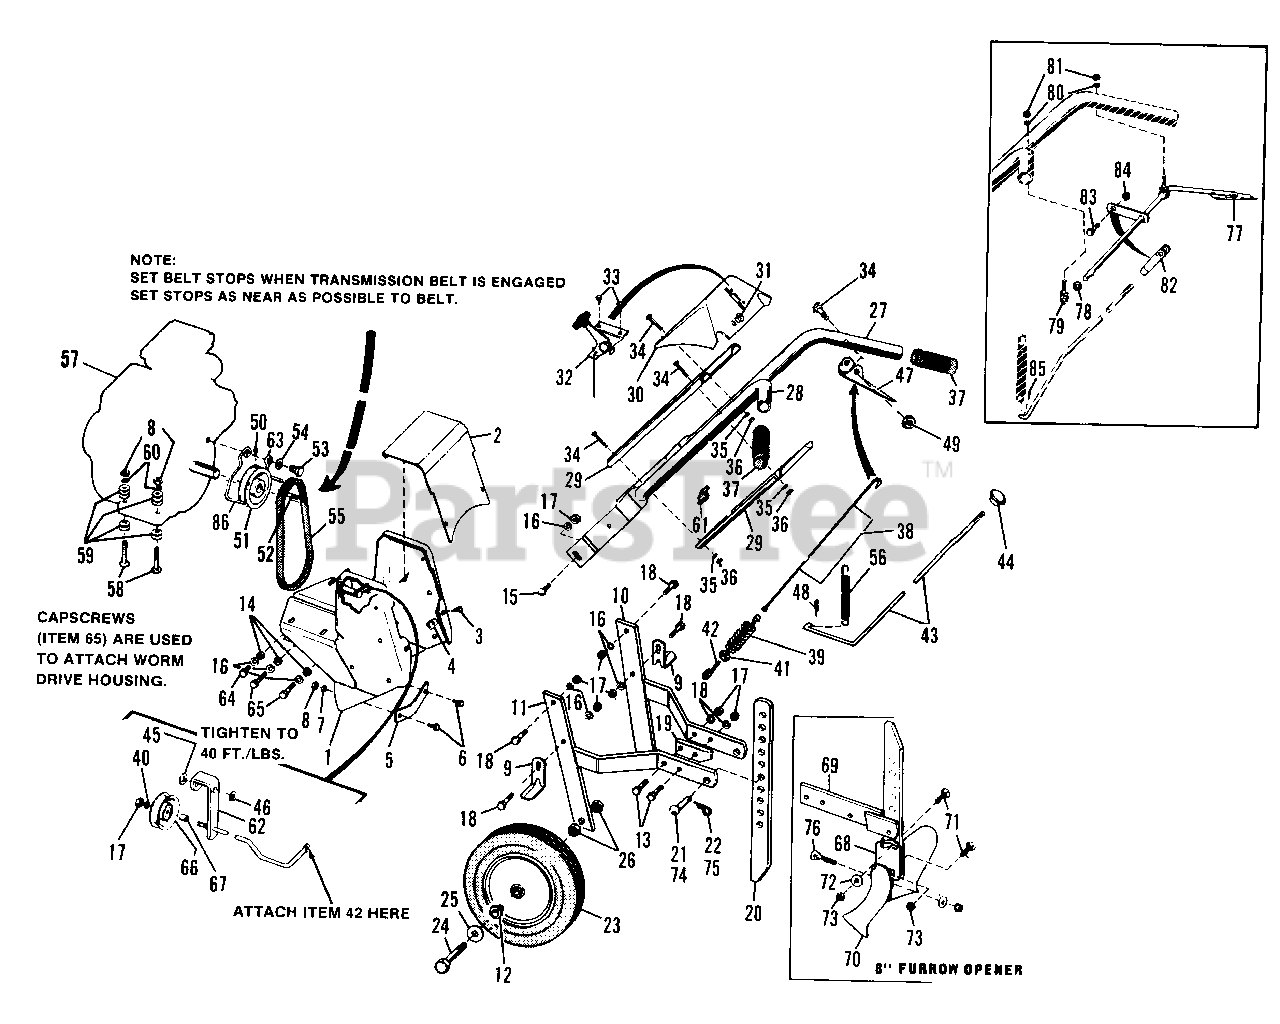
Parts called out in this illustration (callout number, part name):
1	BODY ASSY
2	BODY COVER
3	SCREW, Thumb
4	NUT, Speed
5	SUPPORT, Shaft
6	CAPSCREW, Hex, 5/16-18 x 5/8
7	LOCKWASHER, 5/16
8	NUT, Hex, Full, 5/16-18
10	SUPPORT ASSY, R.H.
11	SUPPORT ASSY, L.H.
12	BUSHING, Wheel
13	CAPSCREW, Hex, 3/8-16 x 1-1/2
14	NUT, Hex, Full, 3/8-16
15	BOLT, Carriage, 3/8-16 x 3/4
16	LOCKWASHER, 3/8
17	NUT, Hex, Full, 3/8-16
18	CAPSCREW, Hex, 3/8-16 x 1-1/4
19	PLATE, Stop
20	BAR, Depth
21	PIN
22	CLIP, Spring
23	WHEEL & TIRE ASSY
24	CAPSCREW, Hex, 1/2-13 x 3-1/4
25	WASHER, Plain, 1/2
26	NUT, Hex, Jam, 1/2-13
27	HANDLE, L.H.
27	HANDLE, R.H.
28	HANDLE, L.H.
29	COVER, Handle
30	HOUSING ASSY, Control
32	THROTTLE ASSY, control
33	SCREW, Self-Tapping, Hex, 1/4-20 x 1/2
34	CAPSCREW, Hex, 1/4-20 x 1-1/2
35	LOCKWASHER, 1/4
36	NUT, Hex, Full, 1/4-20
38	SPRING, Extension
38	ROD, Clutch
39	SPRING
40	LOCK WASHER, 3/8
41	NUT, Hex, Full, #10-24
42	EYEBOLT
43	ROD, Reverse
45	WASHER
46	RING, Retaining
47	GRIP, Clutch
48	PIN, Cotter
49	NUT, Hex, Full, 1/4-20
50	SETSCREW, 5/16-18 x 3/8
51	PULLEY
52	KEY
53	CAPSCREW, Hex, 1/2-20 x 3/4
53	CAP SCREW, Hex, 1/2-20 x 1
54	LOCK WASHER Int. 1/2
56	SPRING
57	ENGINE
58	CAP SCREW Hex, 5/16-18 x 2
59	WASHER, Plain, 5/16
60	LOCK WASHER, 5/16
61	CLIP, Cable
62	LEVER ASSY, Idler
63	STOP, Belt
64	CAPSCREW, Hex, 3/8-16 x 3/4
65	CAPS CREW, Hex, 3/8-16 x 1-1/4
66	PULLEY
67	SPACER
68	HOLDER, Tool
69	SUPPORT ASSY, Extension
70	FURROW OPENER, 8"
71	BOLT, Carriage, 3/8-16 x 1-1/4
72	WASHER, Plain, 3/8
73	NUT, Hex, Full, 3/8-16
74	PIN
75	CLIP, Spring
77	HANDLE ASSY, Control
78	WASHER, Clutch
79	SCREW, Special
80	LOCK WASHER, 1/4
81	NUT, Hex, Full, 1/4-20
83	CAPSCREW, Hex, 5/16-18 x 1
84	LOCKNUT, Hex, Full, 5/16-18
85	PIN, Cotter, 3/32 x 3/4
86	STOP, Belt
